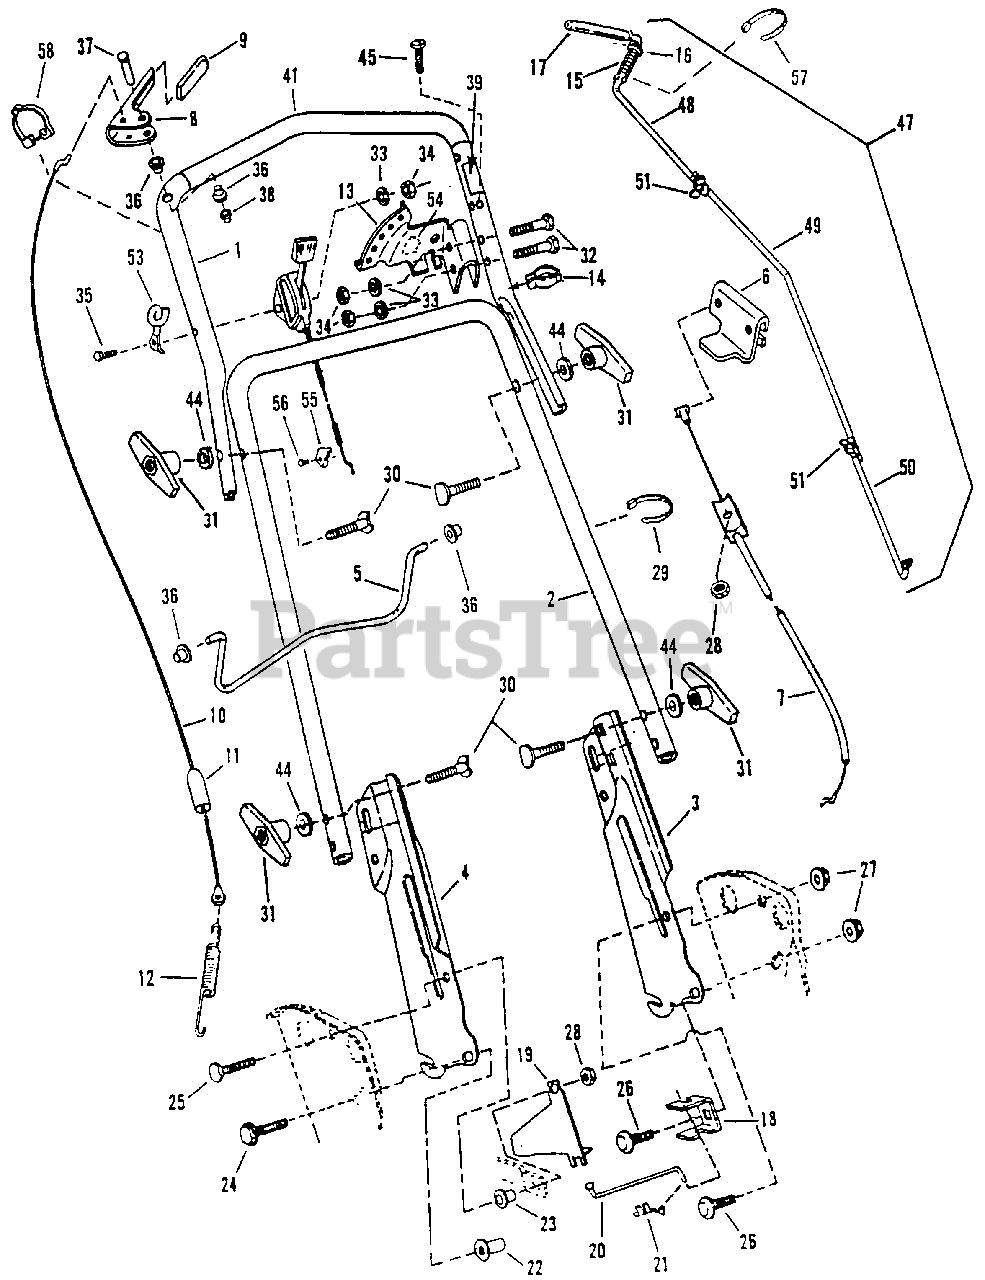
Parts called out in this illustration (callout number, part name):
1	HANDLE, Upper
2	HANDLE, Middle
3	HANDLE, Lower Left Hand
4	HANDLE, Lower Right Hand
5	CONTROL, Blade
6	CLIP, Blade Control
7	CABLE, Blade Control
8	HANDLE, Wheel Drive
9	GRIP, Wheel Drive Handle
10	CABLE, Clutch Pull (Z-BEND)
11	COVER, Vinyl
12	SPRING, Clutch
13	SECTOR, Speed
14	TIE, Wire
15	SPRING, Speed Control
16	WASHER, 3/8" Flat
17	GRIP, Speed Control Handle
18	ANCHOR, Speed Control
19	GUIDE, Lower V Belt
20	ROD, Transfer
21	CLIP, Transfer Rod
22	TEE-NUT, 5/16-18
23	BUSHING, Differential
24	BOLT, 5/16-18 x 3/4" Flange Lock, Grade 5
25	SCREW, 5/16-24 x 1" Hex Cap Grade 5
26	BOLT, 5/16-18 x 5/8" Carriage, Grade 5
27	NUT, 5/16-18 Hex Flange Lock, Grade 5
28	NUT, 5/16-24 Center Lock, Grade 5
29	CLIP, Cable/Wiring
30	SCREW, 5/16-18 x 1-7/8 Curved Head, Grade 2
31	T-KNOB, 5/16-18
32	SCREW, 1/4-28 x 1-3/8 hex Cap, Grade 5
33	WASHER, 1/4 Internal Tooth Lock
34	NUT, 1/4-20 Hex, Grade 5 or B
35	SCREW, 1/4-20 x 2" Hex Cap, Grade 5
36	BUSHING
37	PIN, Clutch Handle
38	PUSH-NUT, (for handle pin)
39	DECAL, Blade Control (L.H. Side)
41	GRIP, Foam
44	WASHER, 5/16 Internal Tooth Lock
45	SCREW, 5/16-24 x 1-1/2" Machine, Grade 5
47	ASSEMBLY, Speed Control Lever
48	ROD, Upper
49	ROD, Intermediate
50	ROD, Lower
51	NUT, 1/4-20 Wing
53	GUIDE, Pull Rope
54	DECAL, Speed Select
55	CLAMP, Casing
56	SCREW, #10-32 x 5/8" Hex Head Cap
57	TIE, Wire
58	CLAMP, 7/8" Double Cable
